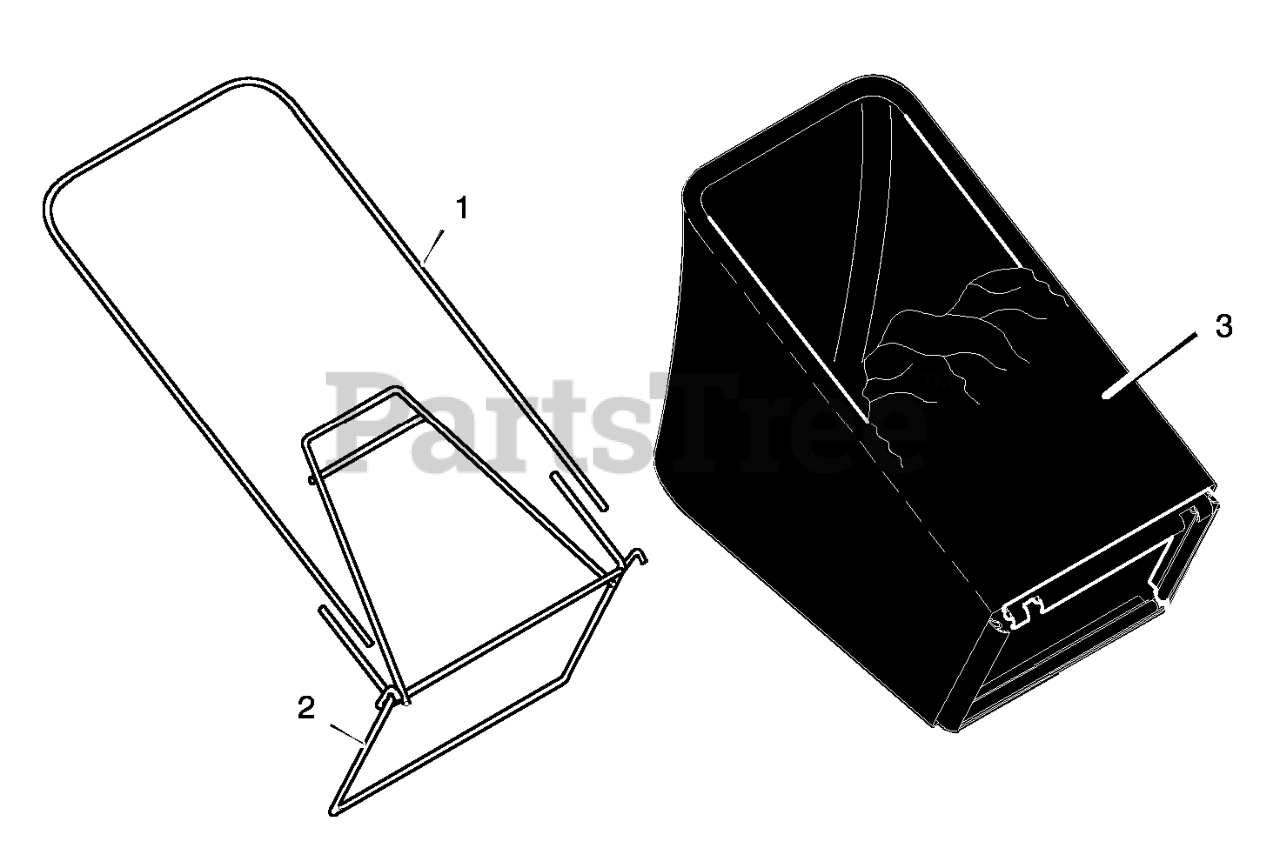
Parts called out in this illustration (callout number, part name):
1	Frame, Top
2	Frame Assembly
3	Bag, Cloth - Black
